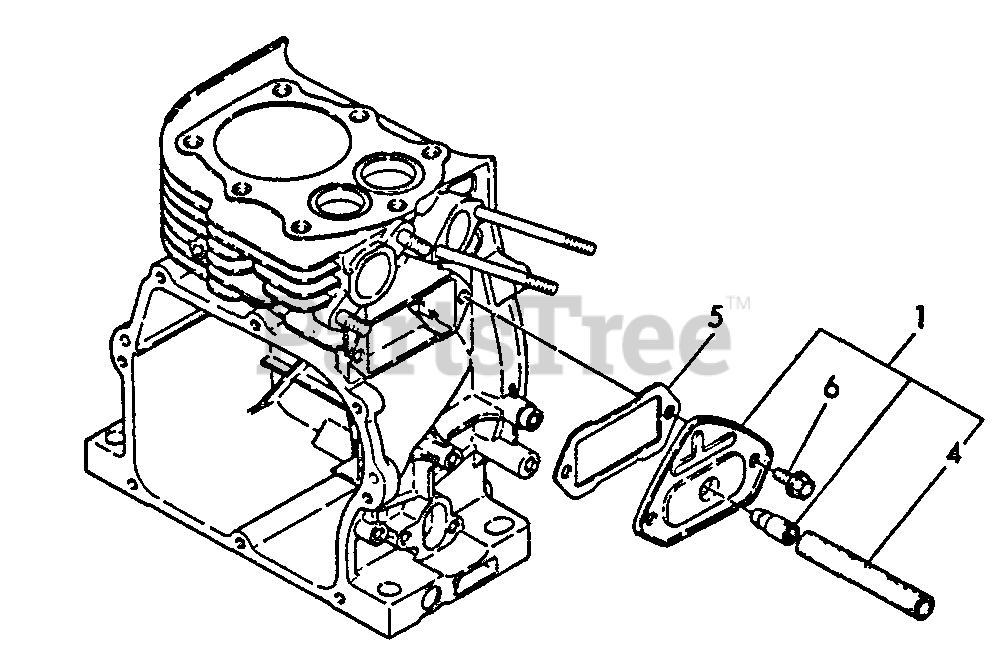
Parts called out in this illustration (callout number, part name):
1	VENT, FUEL TANK
4	PIPE - BREATHER
5	GASKET, BREATHER
6	BOLT - 6X8 -- PLATED
